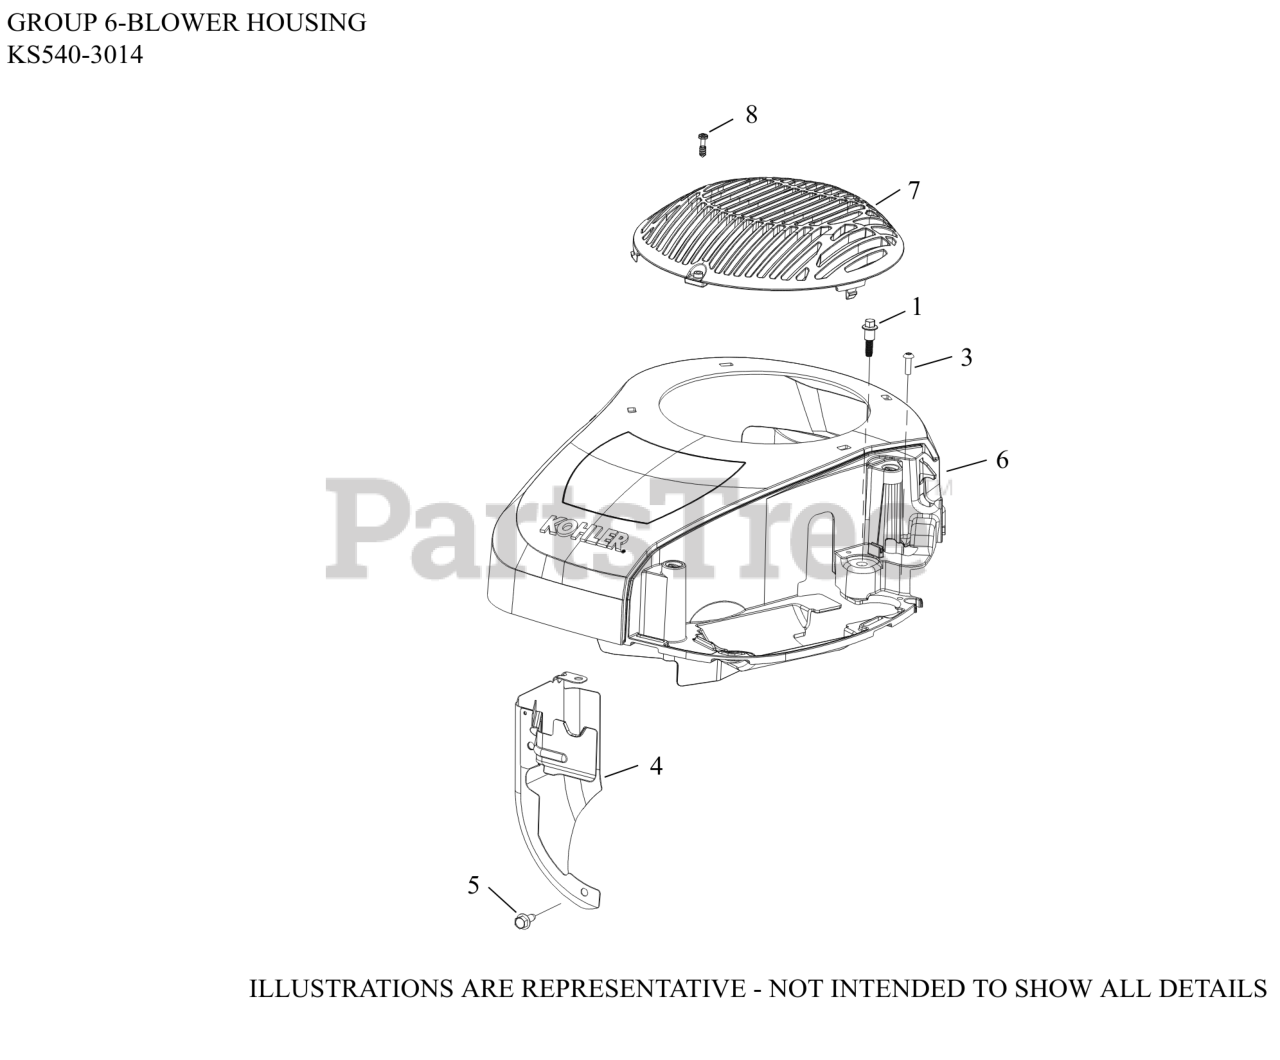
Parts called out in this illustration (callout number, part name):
1	SCREW, SHD THD FRM M6X1X26
3	SCREW, HI-LOW
4	BAFFLE, BARREL ASSY
5	SCREW, THREAD FORMING
6	KIT, BLOWER HOUSING-USE 22 027 05-S
7	GUARD, FIXED
8	SCREW, M5-2.42 (PT) THREAD
